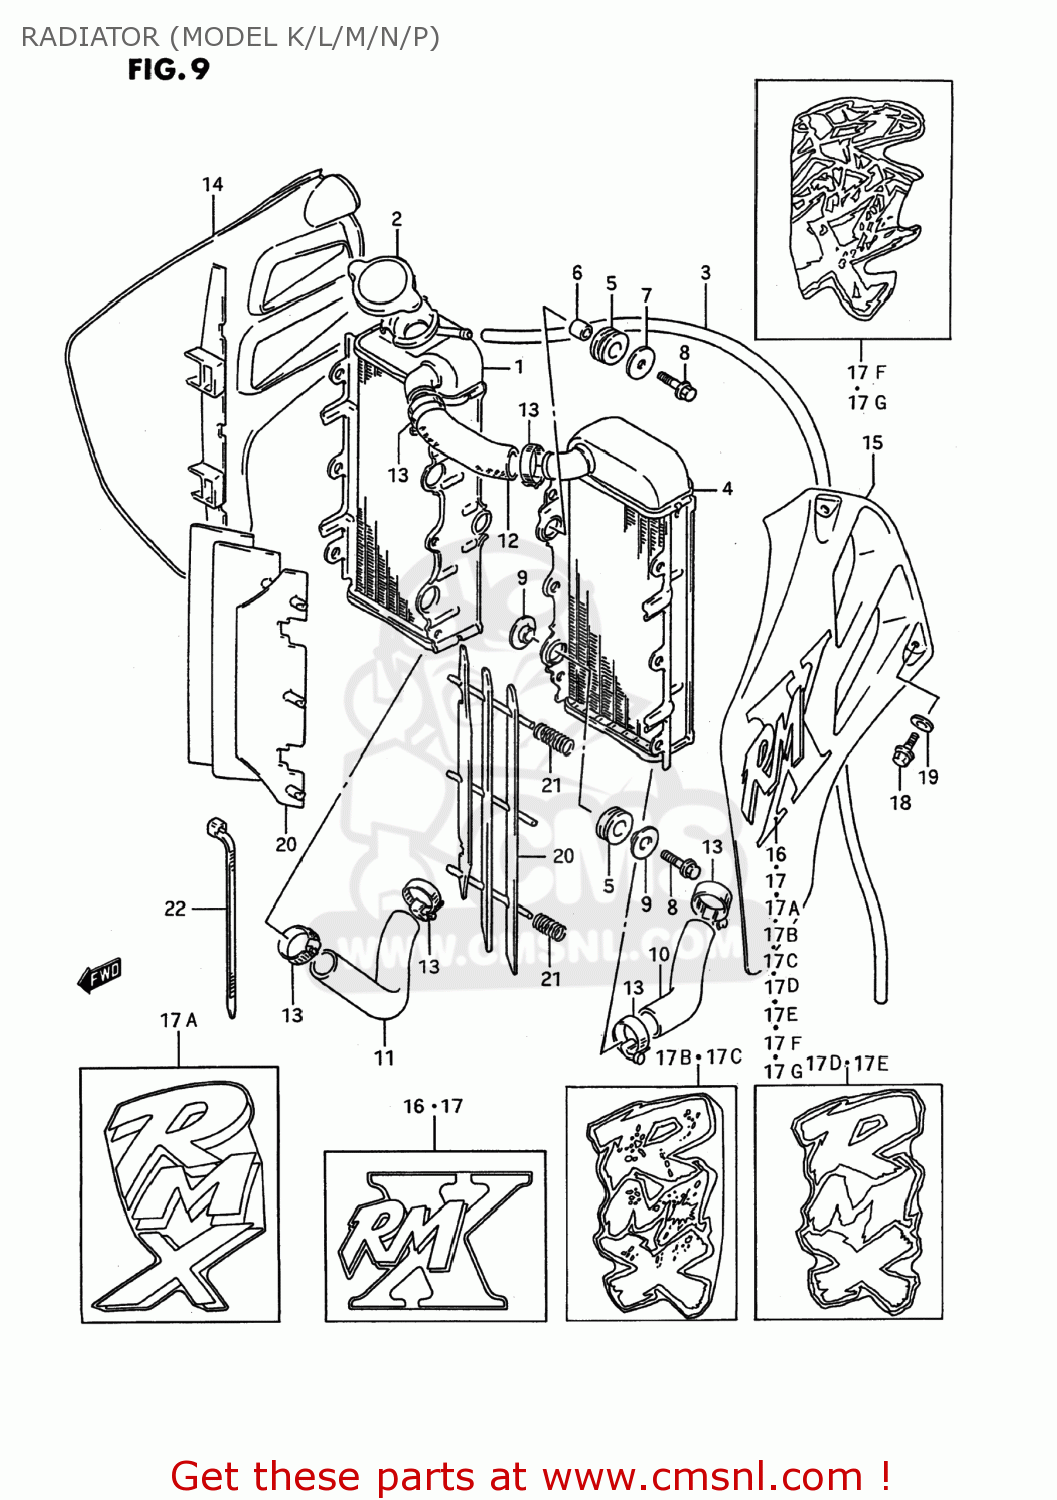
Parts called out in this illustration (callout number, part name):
1	RADIATOR,WATER,R
2	CAP,RADIATOR 1.1
3	HOSE
4	RADIATOR,WATER,L
5	CUSHION,RADIATOR LWR
6	SPACER(6.5X10.5X12)
7	WASHER (6.5X24X1.2)
8	BOLT
9	WASHER,RDTR SPRT
10	HOSE,RADIATOR INLET
11	HOSE,RADIATOR OUTLET
12	HOSE,RADIATOR
13	CLAMP
14	COVER,RADIATOR,R
15	COVER,RADIATOR,L
16	TAPE,RADIATOR COVER,R
17	TAPE
17A	EMBLEM,RADIATOR COVER
17B	EMBLEM,RADIATOR COVER
17C	EMBLEM,RADIATOR COVER
17D	EMBLEM,RADIATOR COVER
17E	EMBLEM,RADIATOR COVER
17F	EMBLEM,RADIATOR COVER
17G	EMBLEM,RADIATOR COVER
18	BOLT
19	WASHER(6.5X18X1)
20	LOUVER,RADIATOR
21	SPRING
22	CLAMP(L:165)
